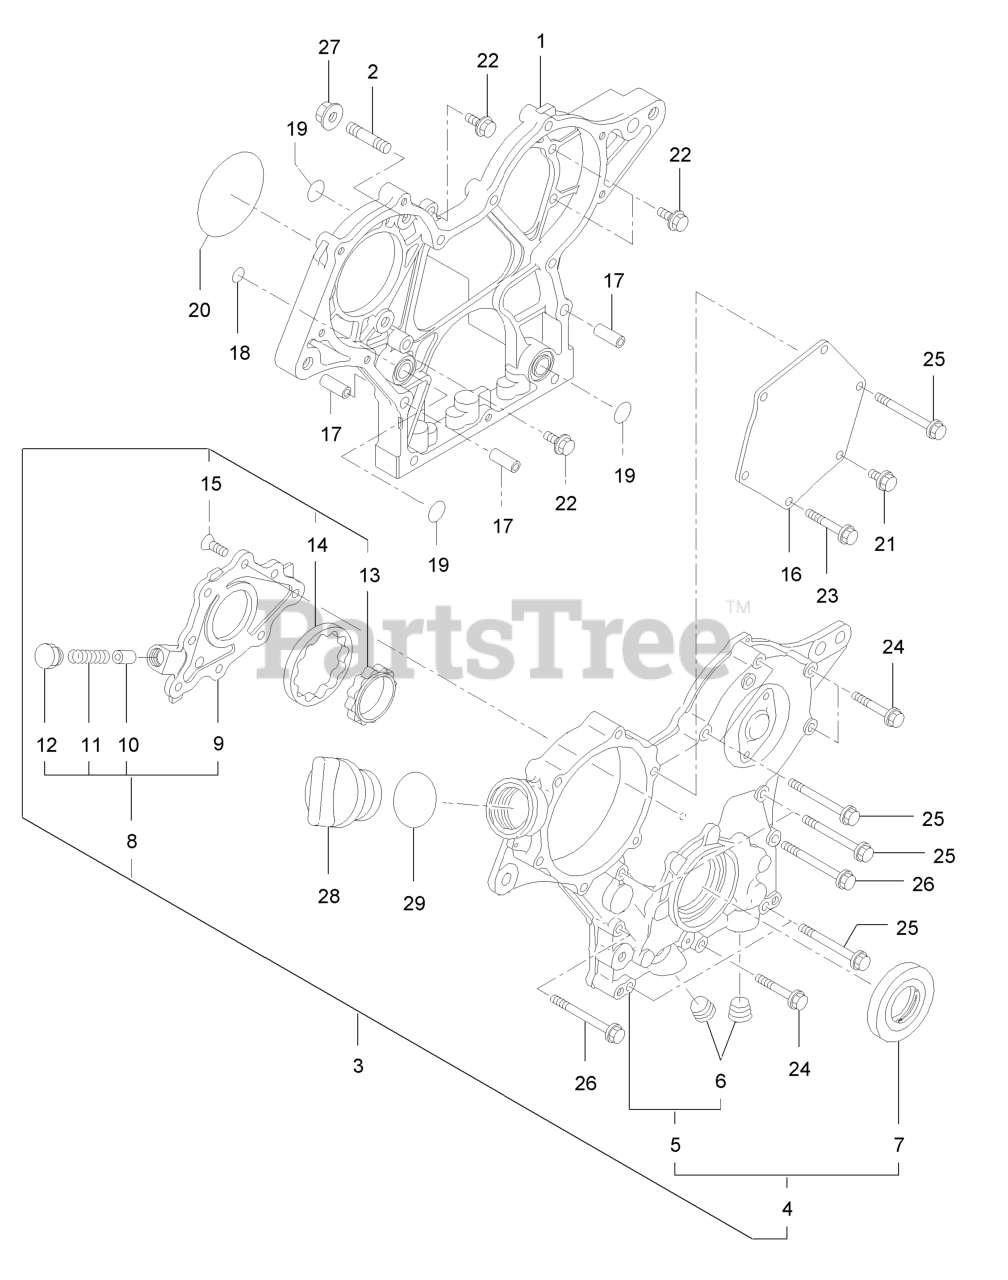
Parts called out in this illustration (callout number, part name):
1	Case-Gear
2	Bolt-Stud
3	Cover ASM-Gear Case
4	Cover Assy-Gear Case
5	Cover-Gear Case
7	Seal-Oil
8	Cover ASM
9	Cover-Pump
10	Valve-Relief
13	Rotor-Inner
14	Rotor-Outer
16	Cover-Pump
17	Pipe-Dowel
28	Cover-Filler
